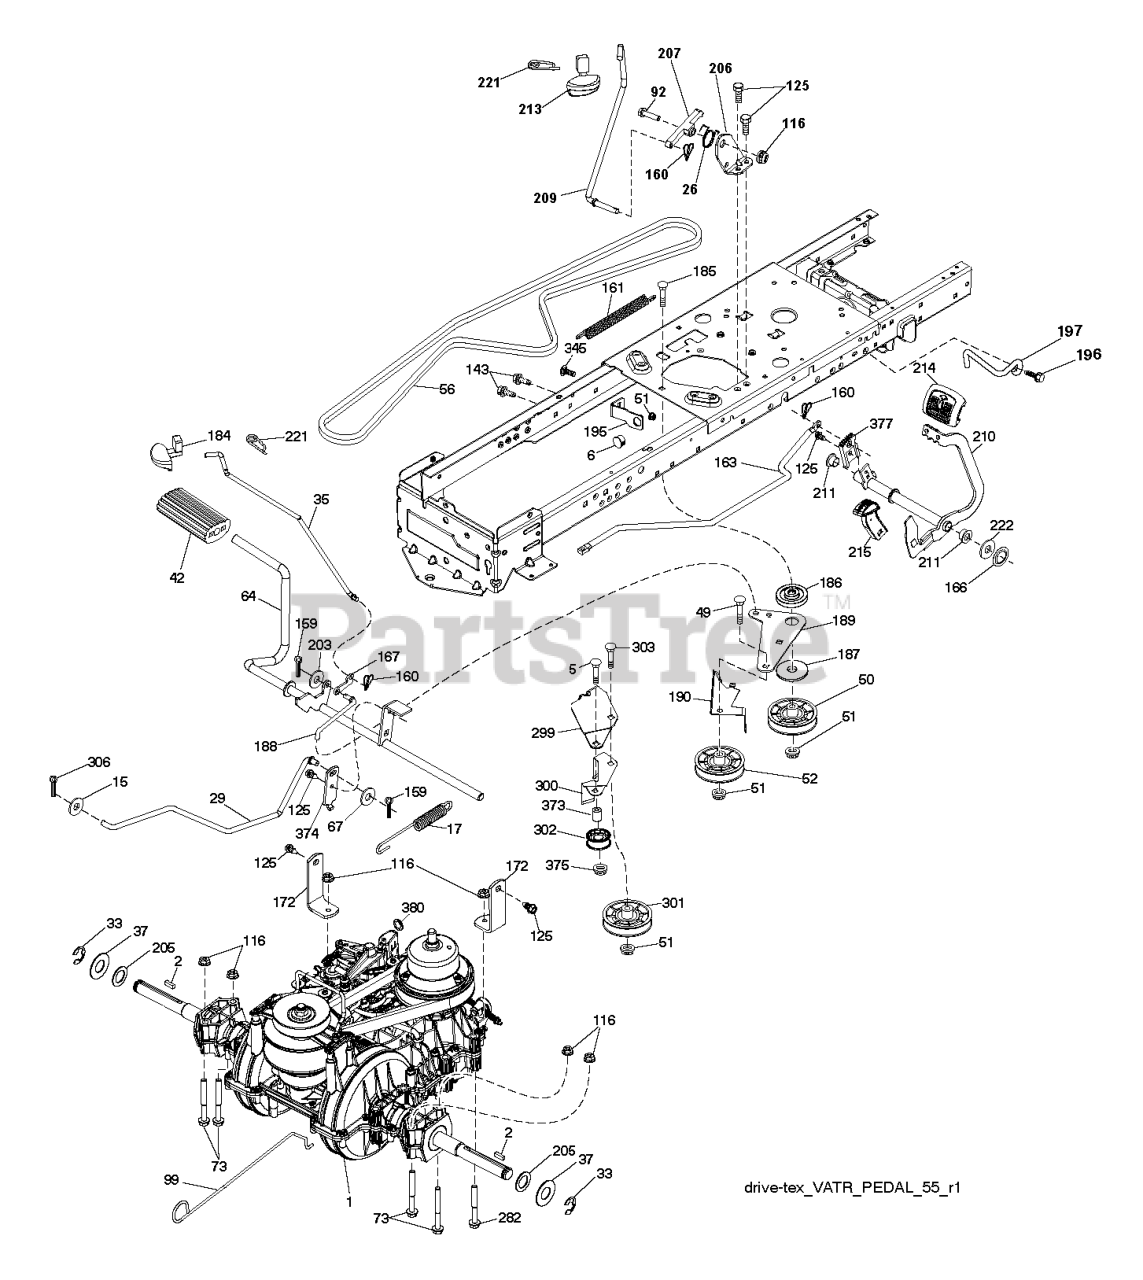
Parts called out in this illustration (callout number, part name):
2	SQUARE KEY
6	BUSHING.SNAP.NYL.BLK.
15	WASHER
17	SPRING BRAKE VARIATOR
17	SPRING.BRAKE.VARIATOR
26	SPRING.RETURN.CRUISE
29	BRAKE.VARIATOR.SD3
35	ROD .BRAKE. PARKING. GT. HUSQ.
37	WASHER.HARDENED
42	PEDAL COVER T
50	IDLER.FLAT.910.OFFSET
51	NUT LOCK FLG 3/8-16 UNC
52	IDLER.V-GROOVE.910.OFFSET
56	BELT.DRIVE.MOWER.TEX.42"
64	SHAFT VARIATOR PEDAL CROSS
67	WASHER.NYLON;13/32X13/16X.109
73	BOLT HEX 5/16-18 GR 5
92	BOLT
99	ROD.BYPASS.VARIATOR.GEN2
116	NUT LOCK HEX FLANGE 5/16-18
125	SCREW
143	Screw 5/16-18 x 1/2 Hex, Self Tapping 5/16-18 x 1/2
159	COTTER PIN
160	RETAINER CLIP
161	SPRING, RETURN LT
163	ROD.CONTROL.PEDAL.VARIATOR
166	NUT.PUSH.625
167	LATCH.BRAKE.SPRING
172	STRAP.TORQUE.VARIATOR.SDX431
184	HANDLE.PARKING.BRAKE.H (BLK)
186	SPACER.RETAINER
187	WASHER 12/32X2X10GA
188	LINK.CLUTCH.GROUND DRIVE.LONG
189	BELLCRANK.GROUND.DRIVE.TEX.
190	KEEPER.BELLCRANK.DRIVE
195	BRACKET.BRAKE.BRAKE.VAR.SD
196	SCREW 3/8-16X1
197	CLUTCH.ANTIROTATION.WIREFORM.
203	WASHER
206	BRACKET.MOUNT.CRUISE.LATCH
207	LATCH.CONTROL.CRUISE.VARIATOR
209	ROD.CONTROL.CRUISE.GT.
210	PEDAL.ASM.ROCKET.VARIATOR.LT
210	WELDMENT.PEDAL.VARIATOR.X431
211	BEARING.NYLON
213	KNOB.CONTROL.CRUSIE.HU
214	PEDAL.FORWARD.PAD.TEX
215	PEDAL.REVERSE.VARIATOR.MS428
221	RETAINER.SPRING.CLIP.H
222	WASHER 21/32 X 1-1/4 X 10 GA.
282	BOLT HEX FLGHD 5/16-18X3 GR. 5
299	BRACKET.MOUNT.IDLERS
300	KEEPER.IDLERS.REAR.VARIATOR
301	PULLEY.IDLER.V-GROOVE
302	PULLEY.IDLER.FLAT.2"
303	BOLT CARRIAGE
306	PIN COTTER
373	SPACER.IDLER
374	ARM.CONTROL.BRAKE
377	GEAR.SECTOR.CRUISE
380	NUT.FLG.NYLOCK.1/4-20.GR.G.ZY
